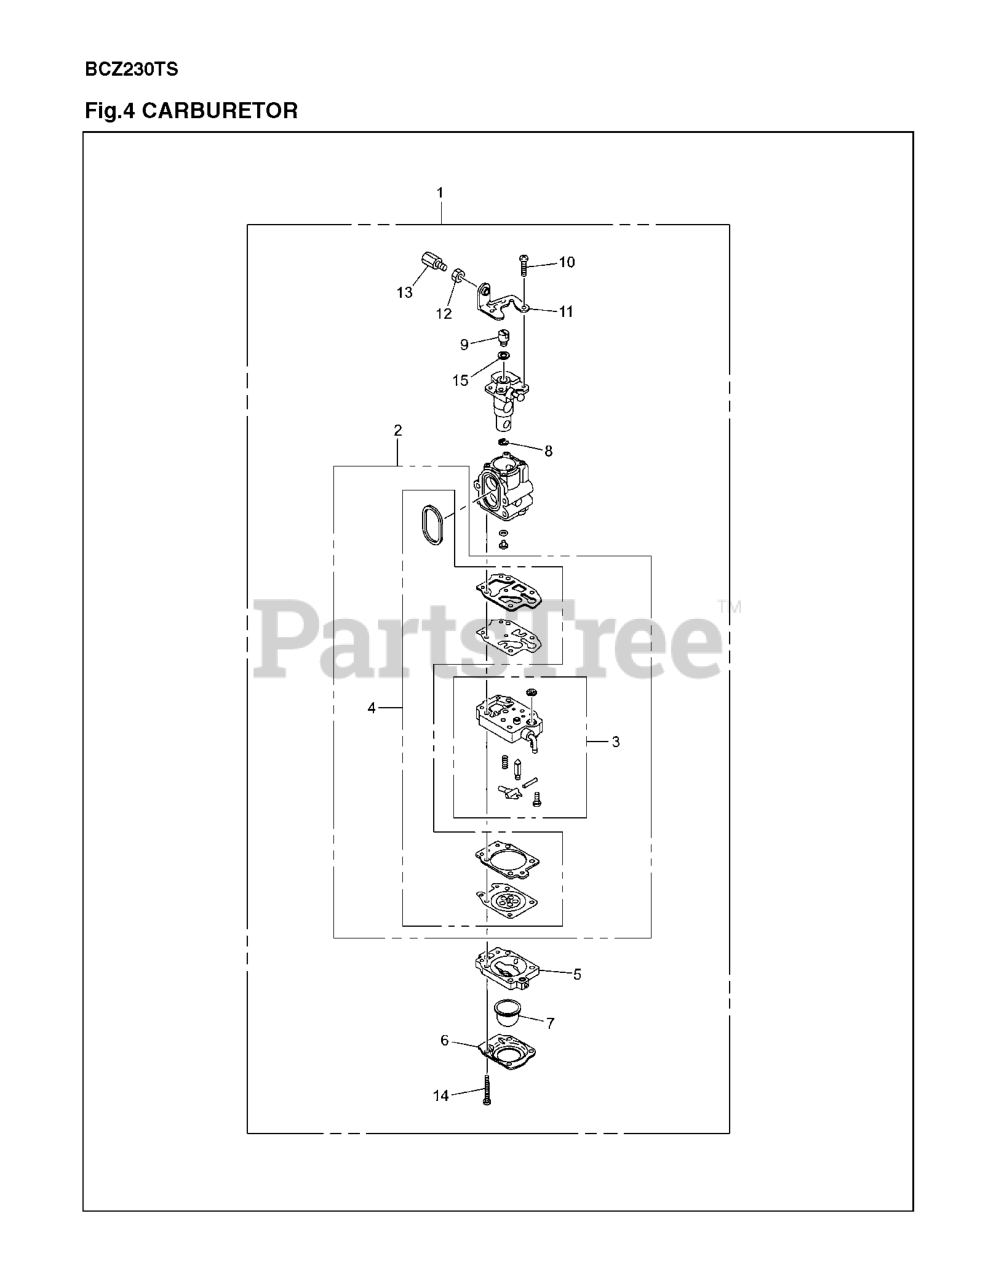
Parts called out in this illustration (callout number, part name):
2	REBUILD KIT
3	CARBURETOR BODY
4	GASKET KIT
6	1OVER
8	RING
9	SWIVEL
10	SCREW
11	BRACKET
12	NUT
13	ADJUSTER
15	WASHER
